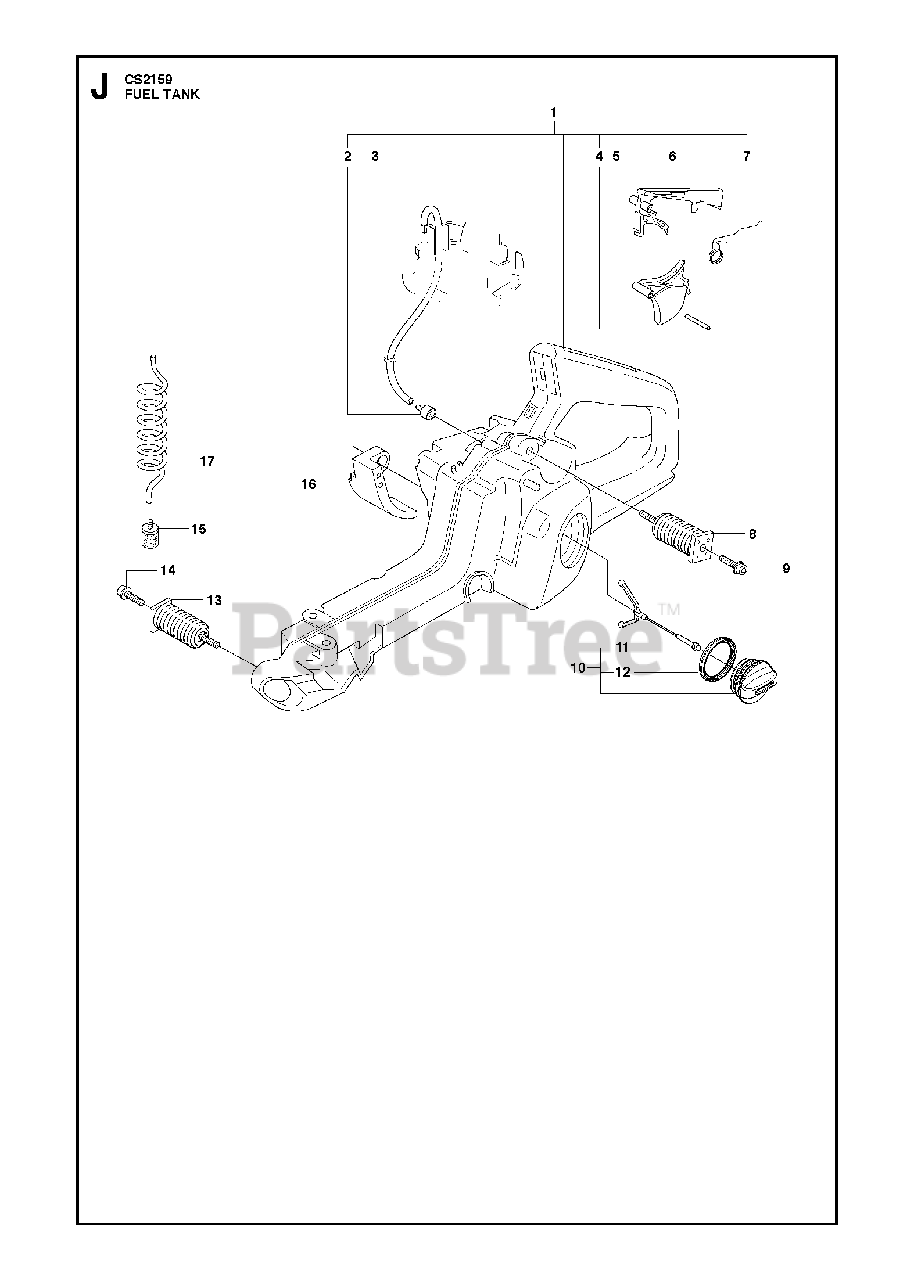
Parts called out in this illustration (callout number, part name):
2	FUEL TANK VENT
3	FUEL HOSE
4	PIN
5	THROTTLE TRIGGER
6	THROTTLE LOCK
7	SPRING
8	VIBRATION ABSORBER
10	TANK CAP
11	HOLDER
12	SEALING
15	FUEL FILTER
16	PROTECTOR
17	FUEL HOSE
